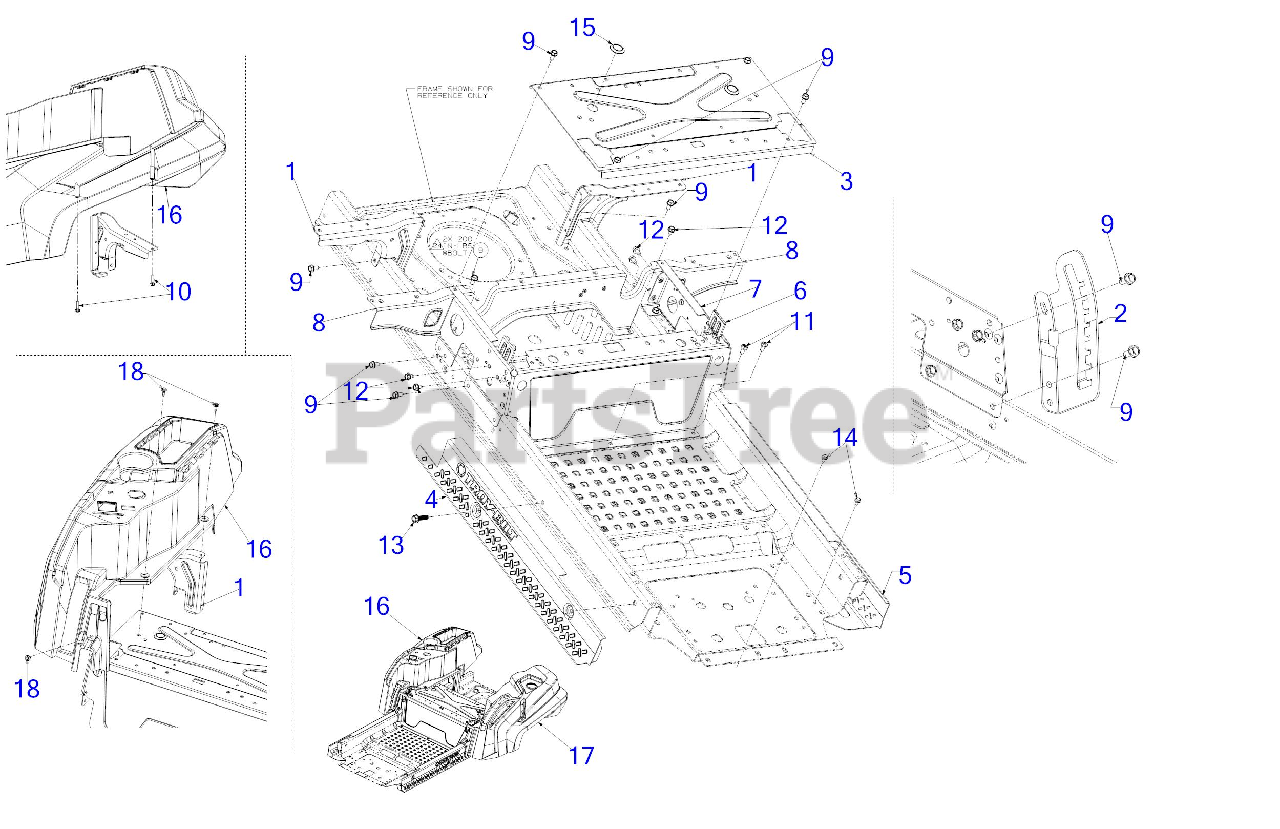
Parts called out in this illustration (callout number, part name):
2	HEIGHT INDEX BRACKET
9	SCREW 5/16-18 x .750
10	SCREW 5/16-14 x 1
11	SCREW 5/16-18 x .750
12	SCREW 5/16-18 x .500
13	SCREW 3/8-16 X1.250
14	SCREW 1/4-20X.625
16	CONSOLE (RH)
17	CONSOLE (LH)
18	SHOULDER SCREW M6-1 .368 X.115
